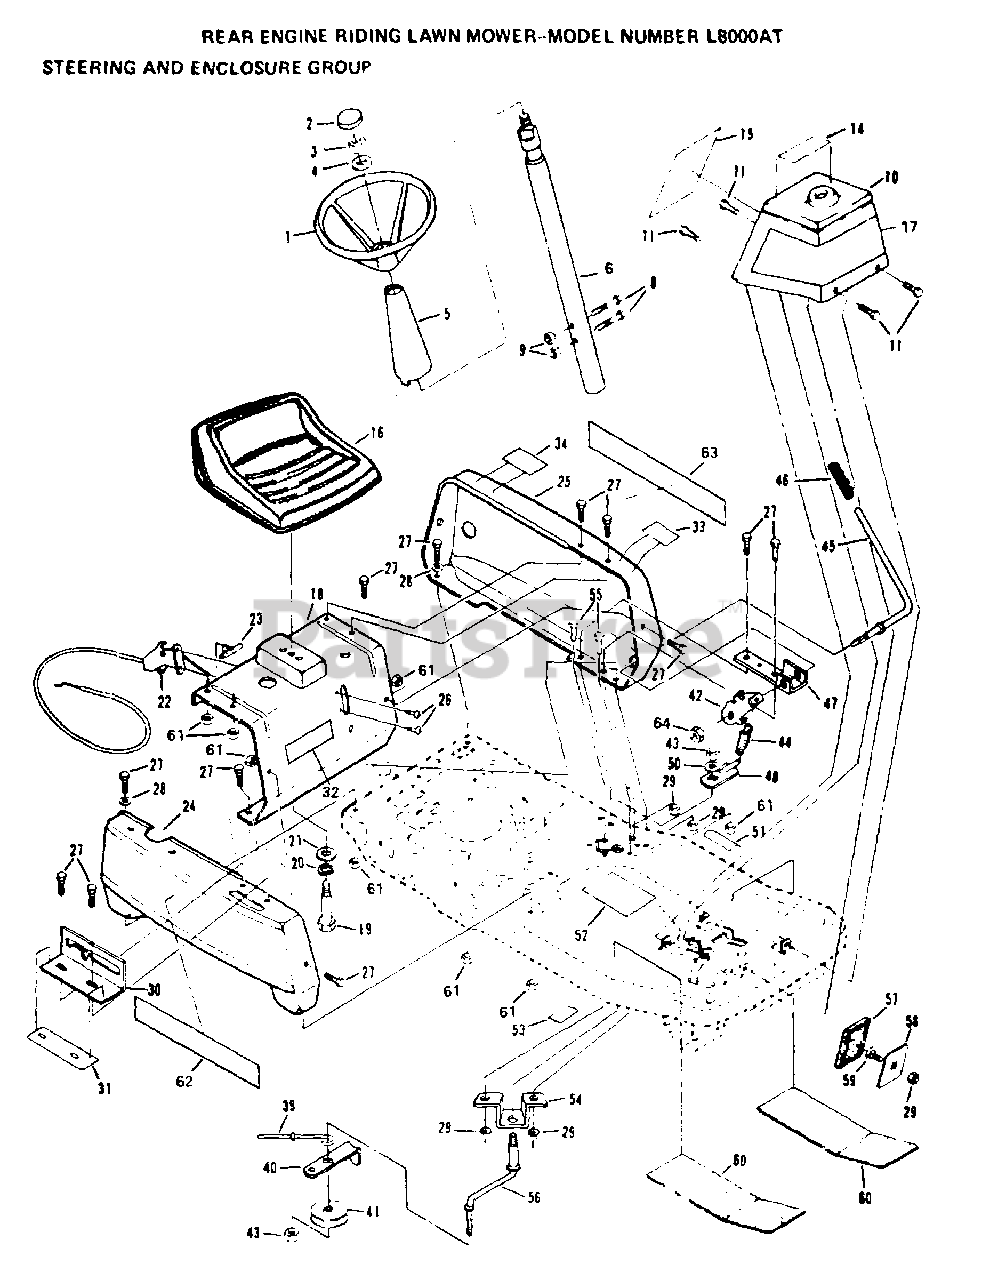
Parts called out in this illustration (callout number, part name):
2	INSERT CAP LT
3	NUT
5	STEERING SHAFT COVER
6	STEERING SHAFT ASSY
11	SCREW LT
14	DECAL - OPERATING INSTRUCTIONS
15	DECAL - INSTRUCTION
18	FRONT PANEL W/SILK SCREEN
21	WASHER
30	SHIFTER GATE T
33	DECAL - BLADE
34	DECAL - ENGINE
40	BELT KEEPER T
41	IDLER PULLEY T
45	LEVER.CLUTCH.BLAD
48	CONTROL ARM ASSY
51	DECAL - ENTER & EXIT
52	DECAL - BRAKE INSTRUCTION
54	IDLER SUPPORT BKT
55	BOLT
57	FOOT PAD LT
59	BOLT
62	DECAL - FENDER
63	DECAL - FENDER
64	LOCKNUT
